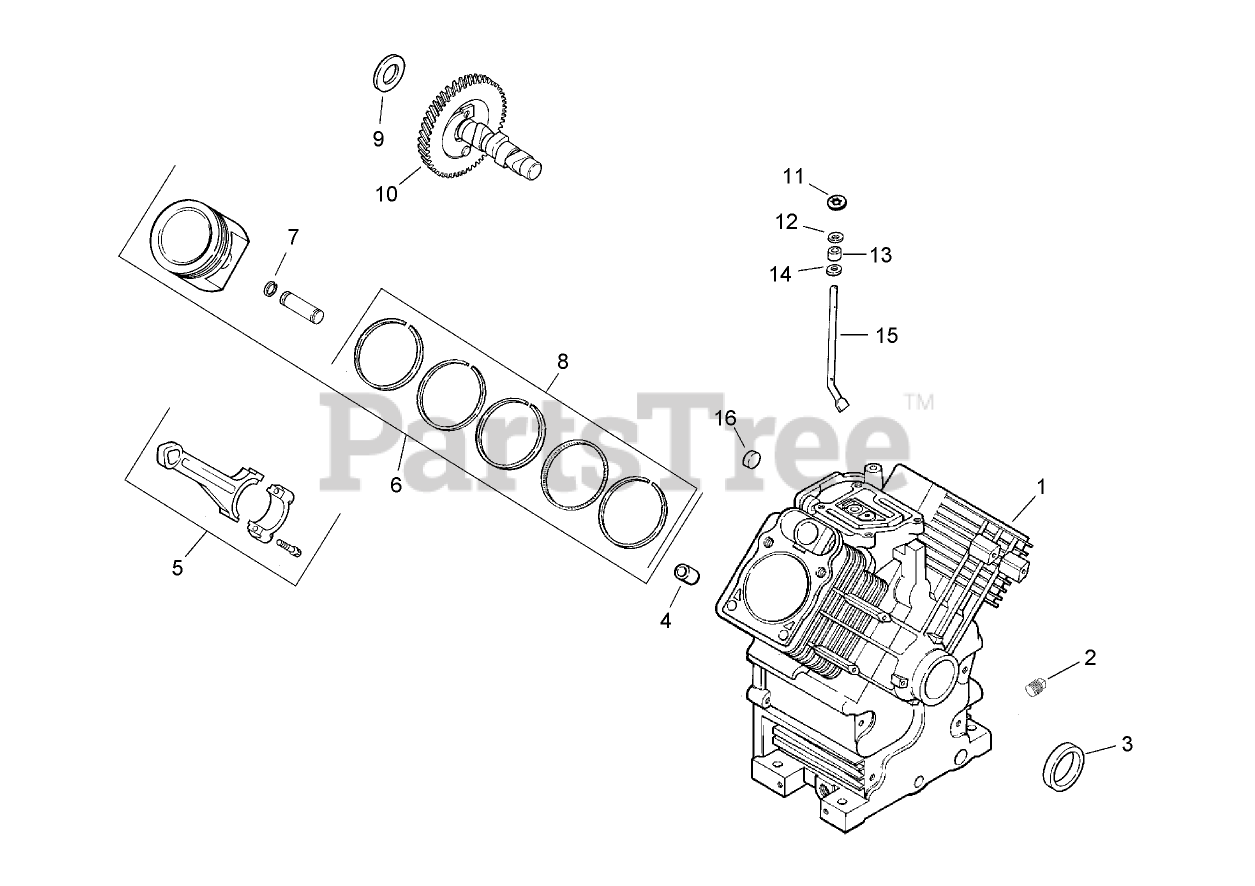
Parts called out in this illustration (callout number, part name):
1	Crankcase (USE: Short Block or Miniblock)
2	PLUG-PIPE, SQ HD (3/8)
3	SEAL-OIL
4	Pin-Locating
5	Rod-Connecting (Standard)
5	Rod-Connecting (.25)
6	Piston w/Ring Set (Std.) (Includes 7,8)
6	Piston w/Ring Set (.08) (Includes 7,8)
7	RETAINER-PIN, PISTON
8	Ring Set (.25)
9	SHIM-CAMSHAFT (RED .032)
9	SHIM-CAMSHAFT (BLACK .04)
9	SHIM-CAMSHAFT (WHITE .028)
9	SHIM-CAMSHAFT (BLUE .03)
9	SHIM-CAMSHAFT (YELLOW .034)
9	SHIM-CAMSHAFT (GREEN .036)
9	SHIM-CAMSHAFT (GRAY .038)
10	Camshaft Kit
11	RETAINER-RING
12	WASHER-FLAT (9MM)
13	SEAL-CROSS SHAFT, GOVERNOR
14	WASHER-FLAT (11/32)
15	Shaft-Cross, Governor
16	PLUG-CUP
